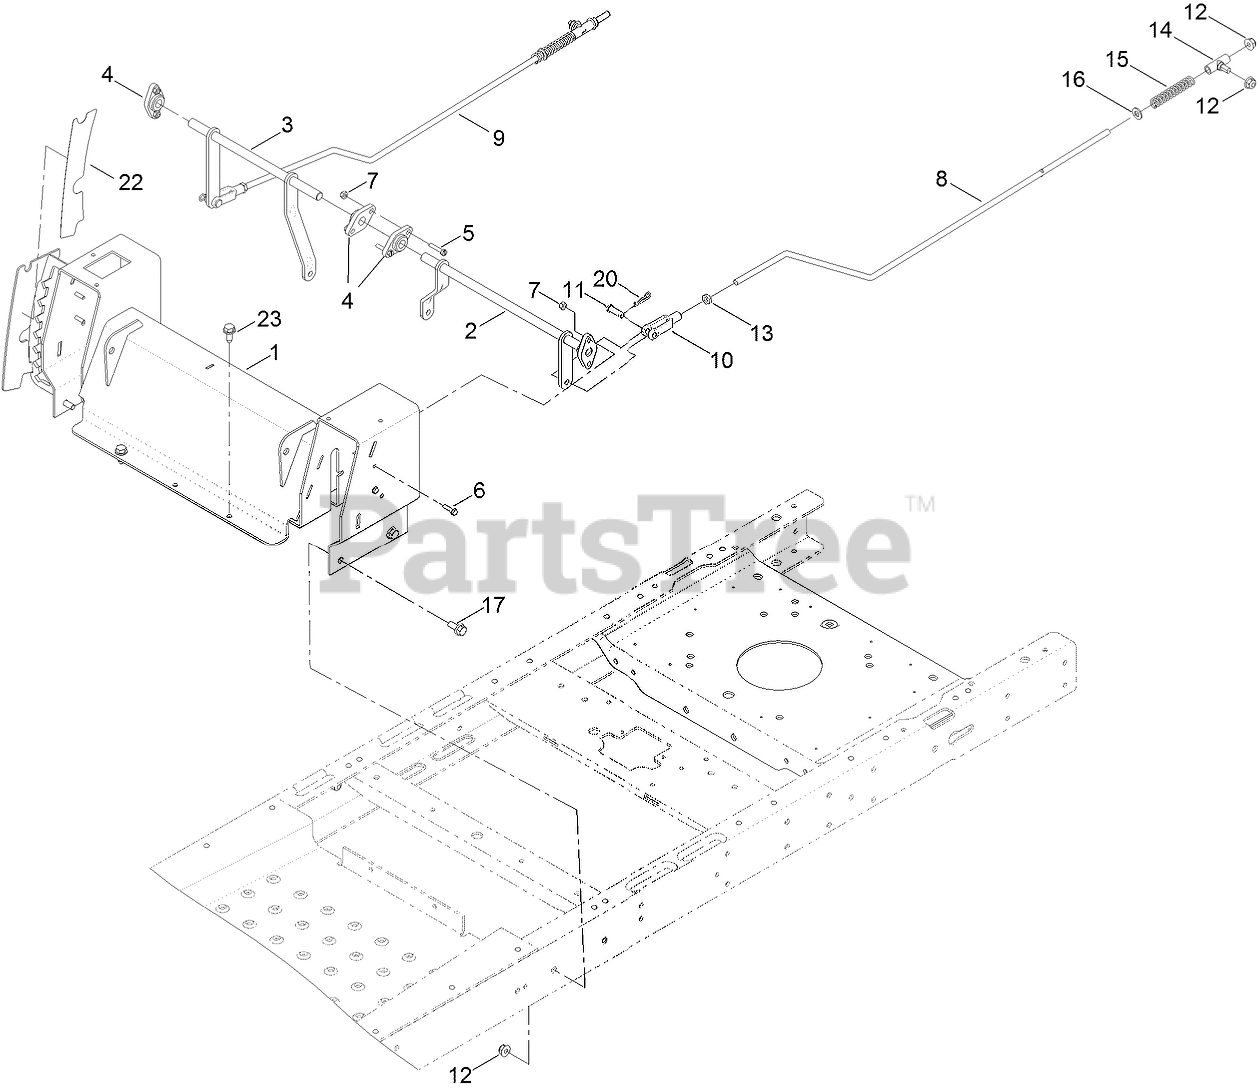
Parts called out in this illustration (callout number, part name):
1	BOX-CONTROL, WIDE
2	BELLCRANK-LH, WIDE
3	BELLCRANK-RH, WIDE
4	BEARING-FLANGE
6	SCREW-HWH
7	NUT-LOCK, NI
8	ROD-HYDRO, LH
9	ROD-HYDRO, RH
10	YOKE-ADJUSTABLE
11	PIN-CLEVIS
12	NUT-HF, NI
13	NUT-JAM
14	MOUNT-ROD, HYDRO
15	SPRING-RETURN, NEUTRAL
16	WASHER-PLAIN
17	SCREW-HHF
20	PIN-COTTER
22	DECAL-HOC
23	SCREW-HWHTF
